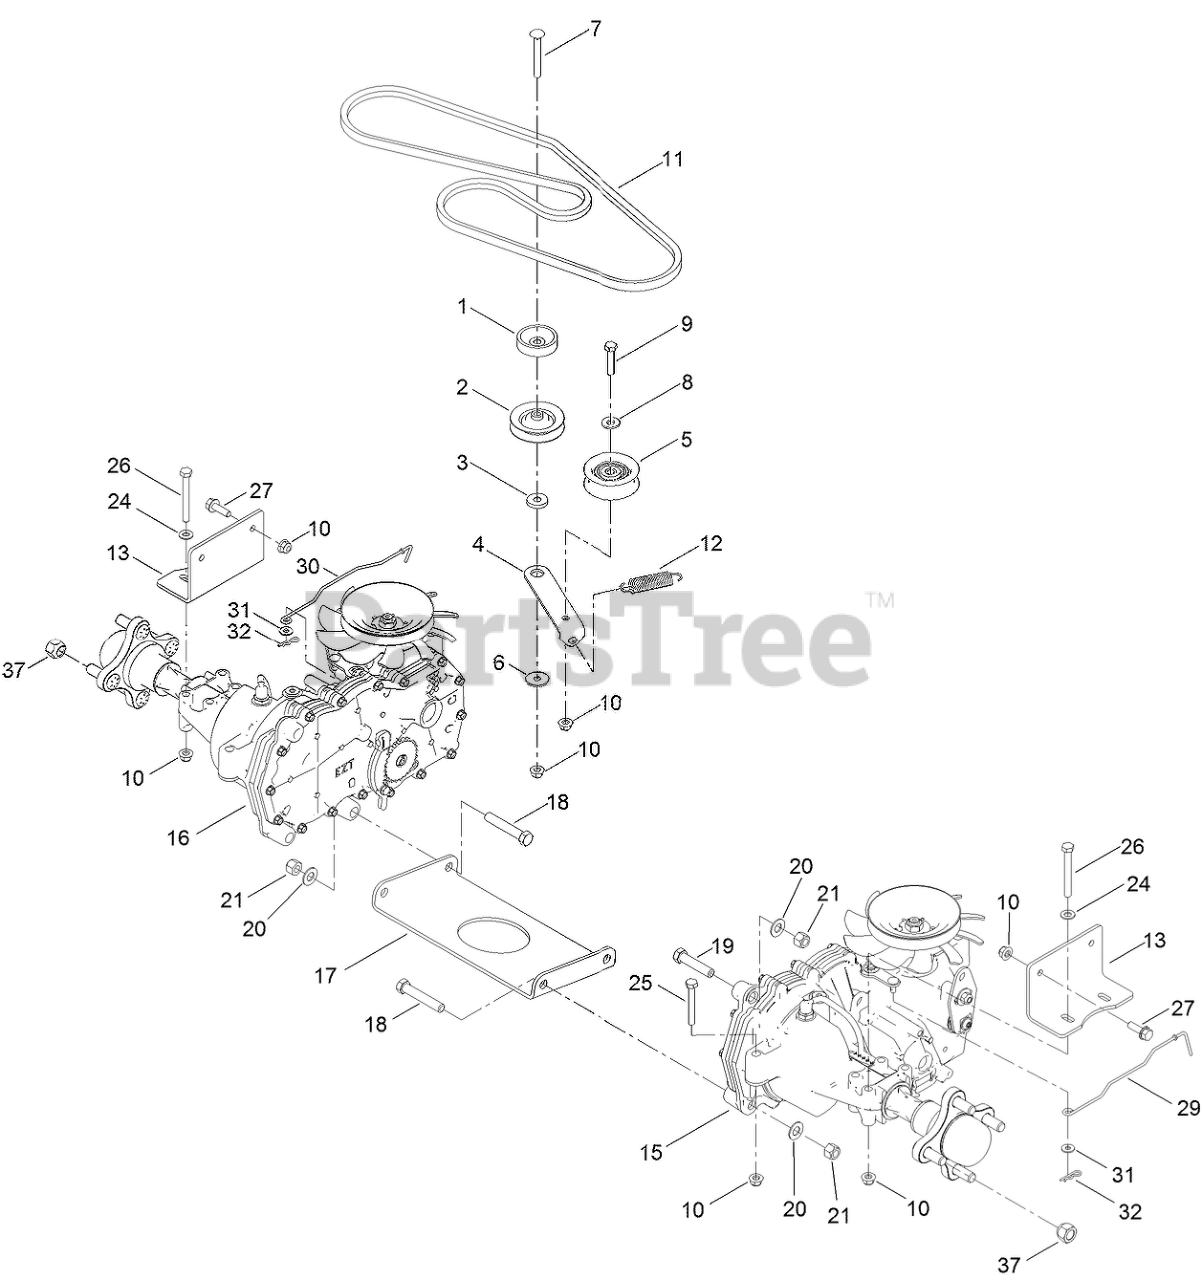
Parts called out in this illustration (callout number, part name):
1	SPACER
2	PULLEY-IDLER
3	SPACER-ARM, IDLER
4	ARM-IDLER
5	PULLEY-IDLER, FLAT
6	WASHER-PIVOT
7	SCREW-CARR
8	WASHER-FLAT
9	SCREW-HH
10	NUT-HF, NI
11	V-BELT
12	SPRING-PEDAL, RETURN
13	MOUNT-HYDRO
15	LH HYDRO TRANSMISSION ASM
16	RH HYDRO TRANSMISSION ASM
17	PLATE-CROSS, HYDRO
18	SCREW-HH
19	SCREW-HH
20	WASHER-FLAT
21	NUT-LOCK, NI
24	WASHER-PLAIN
25	SCREW-HH
26	SCREW-HH
27	SCREW-HHF
29	ROD-BYPASS, LH
30	ROD-BYPASS, RH
31	WASHER
37	NUT-LUG
